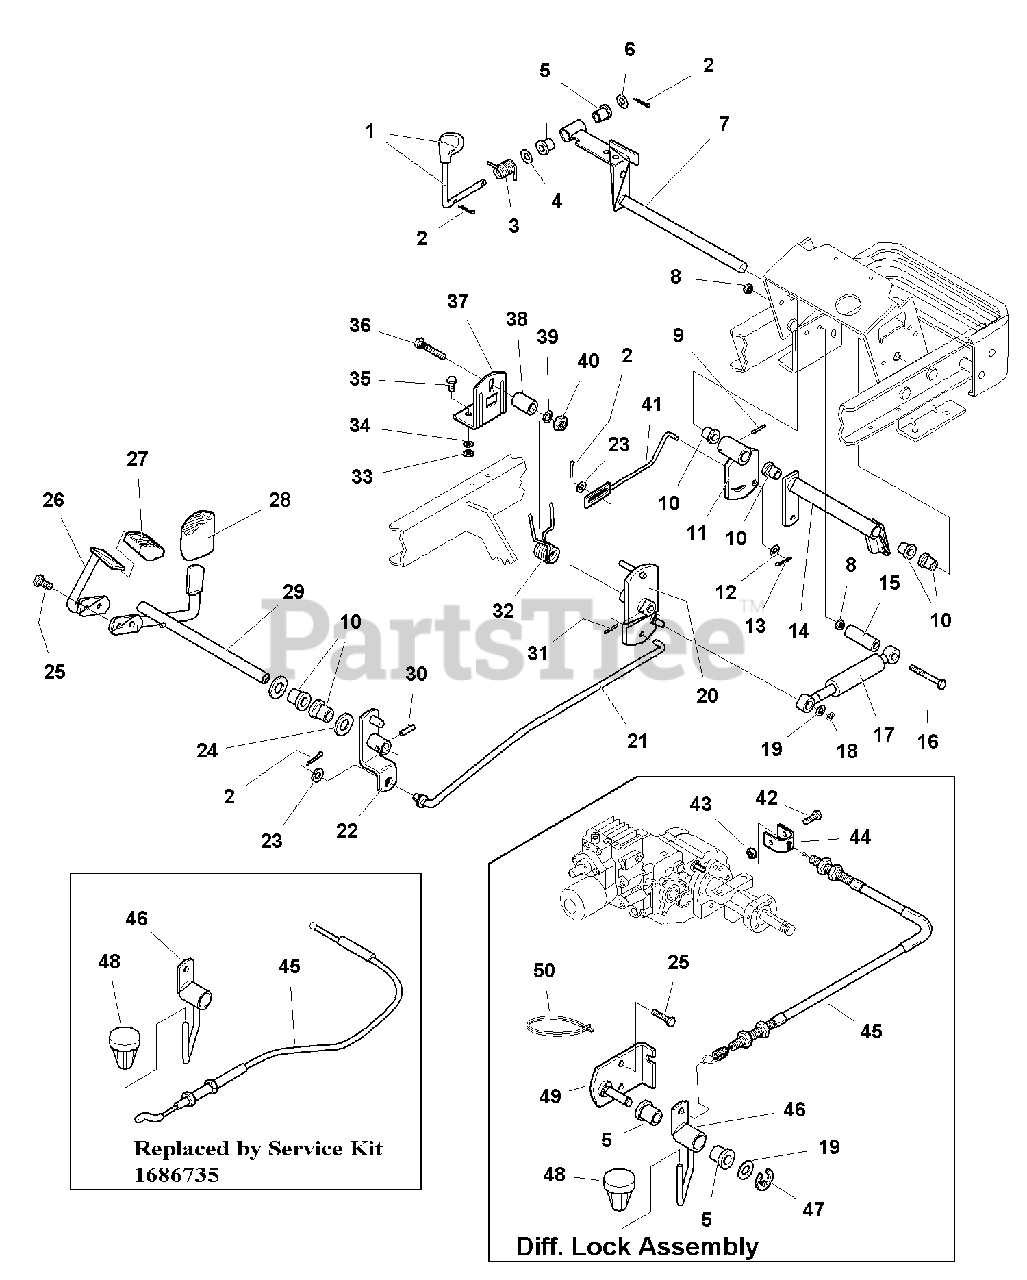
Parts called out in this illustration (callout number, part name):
1	KNOB, Cruise Control
2	PIN, Cotter, 3/32 x 3/4
3	SPRING, Torsion
4	WASHER, 1/2 x 1-1/4
5	BUSHING, Nylon
7	HANDLE ASSEMBLY, Cruise
8	NUT, Hex, Whizlock, 7/16-14
9	PIN, Roll, 1/4 x 1-1/4
11	CONTROL ARM ASSEMBLY, Cruise
12	WASHER, Plain, 3/8
13	PIN, Cotter, 1/8 x 3/4
14	CROSS SHAFT ASSEMBLY, Brake
15	SPACER, Shock Absorber
16	CAPSCREW, Hex Head, 7/16-14 x 4
17	SHOCK ABSORBER
19	WASHER, 1/2
20	LEVER ASSEMBLY, Control
21	ROD, Pedal to Lever
22	CONTROL ARM ASSEMBLY
23	WASHER, Plain, 7/8
24	WASHER, 3/4
25	CAPSCREW, Taptite, 5/16-18 x 3/4
26	PEDAL, Foot, Hydro
27	PAD, Pedal (Forward)
28	PAD, Pedal (Reverse)
29	FOOT PEDAL ASSEMBLY
30	PIN, Roll, 1/4 x 1-1/4
31	PIN, Roll, 1/4 x 1-3/4
32	SPRING, Torsion
33	NUT, Hex, Full, 5/16-18
34	LOCKWASHER, 5/16
35	CARRIAGE BOLT, 5/16-18 x 3/4
36	CARRIAGE BOLT, 3/8-16 x 2-1/4
37	PLATE, Pedal Stop
38	TUBE, Neutral
39	LOCKWASHER, 3/8
40	NUT, Hex, Jam, 3/8-16
41	ROD, Cruise (To Lever Assembly)
42	CAPSCREW, 1/4-20 x 3/4
43	NUT, Hex Nylon Lock, 1/4-20
45	CABLE, Diff Lock
46	ARM ASSEMBLY, Diff Lock
47	E-CLIP, Retaining Ring
48	KNOB, Hole, 1/2 x 1-3/4, 2-11/16 Long
48	BUTTON, Diff Lock
49	PIVOT ASSEMBLY, Diff Lock
